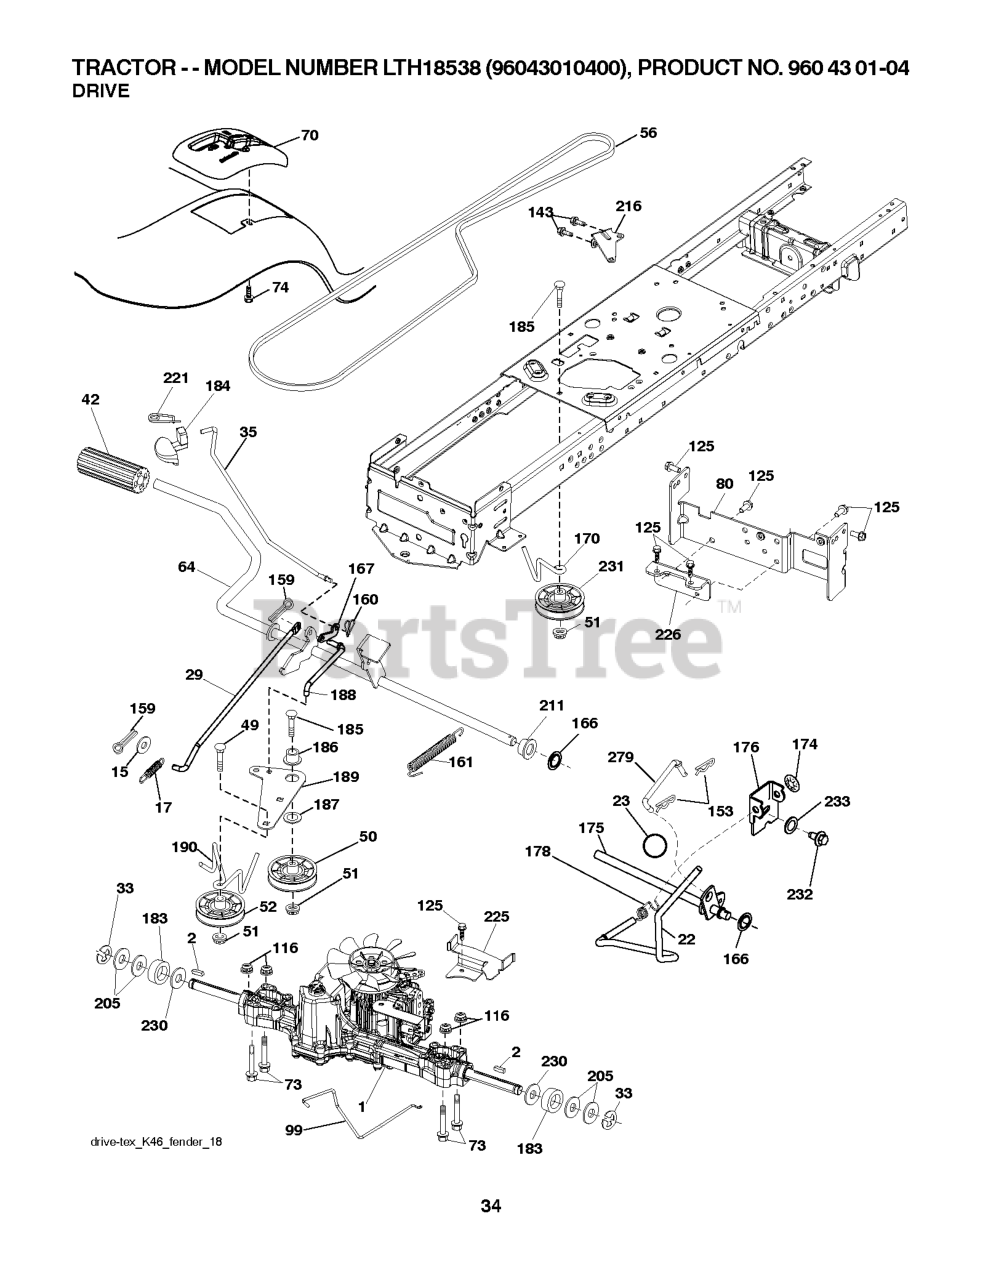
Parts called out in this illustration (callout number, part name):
1	TRANSAXLE.K46A
2	SQUARE KEY
15	WASHER
17	SPRING.BRAKE.K46.GREEN
22	ROD.SHIFT.FENDER.TLT.2006
23	KNOB.DELUXE.(PISTOL.GRIP).BLAC
29	ROD.BRAKE.K46
35	ROD.CNTRL.PARK.PREDATOR.LT.TEX
42	PEDAL COVER T
50	IDLER.FLAT.910.OFFSET
51	NUT LOCK FLG 3/8-16 UNC
52	IDLER.V-GROOVE.910.OFFSET
56	V-BELT.MOWER.92.40.42/K46
64	SHAFT.ASM.PEDAL.BRAKE.
70	CONSOLE SHIFT
73	BOLT HEX 5/16-18 GR 5
74	SCREW.HI-LO.CONSOLE
80	STRAP TORQUE
99	ROD.SPRING.BYPASS.K46.LT.Z
116	NUT LOCK HEX FLANGE 5/16-18
125	SCREW
143	Screw 5/16-18 x 1/2 Hex, Self Tapping 5/16-18 x 1/2
153	RETAINER M
159	COTTER PIN
160	RETAINER CLIP
161	SPRING, RETURN LT
166	NUT.PUSH.625
167	LATCH.BRAKE.SPRING
170	KEEPER.CENTER SPAN.1.688
174	NUT.PUSH.500.2006
175	SHAFT.ASM.SHFT.T2.TLT
176	ARM.CLEVIS.ROD.SHIFT
178	SPRING.SHIFT.GT2006
183	SPACER AXLE
184	HANDLE PARKING BRAKE
186	SPACER.RETAINER
187	WASHER 12/32X2X10GA
188	RP.LINK.CLUTCH.GROUND.DRIVE
189	BELLCRANK.GROUND.DRIVE.TEX.
190	KEEPER.BELLCRANK.DRIVE
211	BUSHING.SHAFT.BRAKE.HAND
216	BRACKET.PULLEY.IDLER.W/TEX
221	RETAINER.SPRING.CLIP.H
225	KEEPER.BELT.TRANSAXLE.K46
226	BRACKET.MOUNT.TORQUE.K46.TLT
227	SCREW.THDROL.5/16-18X3/4.TTY
230	WASHER.HARDENED
231	IDLER.V-GROOVE.1.688.OFFSET
232	BOLT FIN HEX 7/16-14 X 1
233	WASHER SERRATED
279	LINK.SHIFT.
